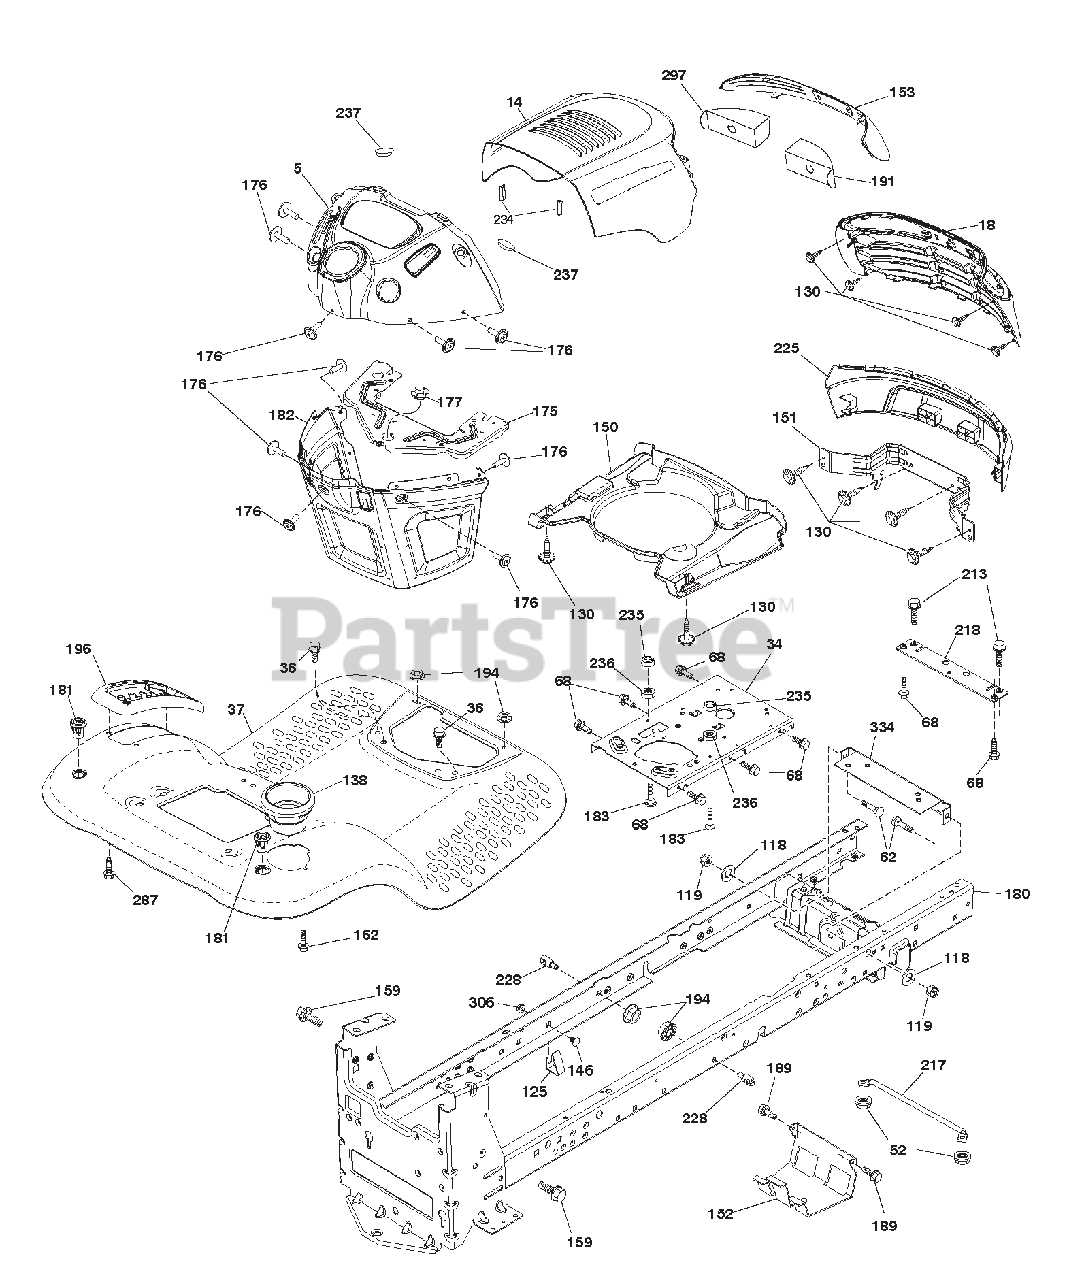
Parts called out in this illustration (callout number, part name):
18	GRILLE
34	PLATE.ENGINE.WELDED.CHASSIS
36	SCREW.5/16-18X3/4.SMGML.TAP/R
37	FENDER TLT W/CPH W/FW 422
52	Nut, Hex, Crownlock 5/16-18
62	Bolt 3/8-16 x 1 Gr. 5
68	SCREW.THDROL.5/16-18 X 1/2TYTT
118	WASHER.13/32 X 13/16 X 16 GA.
119	Nut, Hex, Crownlock 3/8-16
125	CLIP.FUEL.LINE
138	CUPHOLDER TL TEX 428
150	AIR DUCT.INTAKE.B&S
151	Bracket Pivot
152	SHIELD.BROWNING.W/TEX
153	LENS, ARIENS
159	SCREW.HEXWSH THDR3/8-16X3/4.BL
162	SCREW.HEX.WSH.HI-LO.1/4X1/2UNC
175	CROSSMEMBER.LT
176	SCREW.#10-24X5/8.RND.QUDRX.GIM
177	BUSHING.STEERING.LT
180	CHASS WLDMT TL 12 GA/2PC 18/22
181	BUSHING MNT FEND CRGO BLK TEX
182	DASH LOWER
183	BOLT.FIN.HEX.5/16-18 UNC X1-1/
189	SCREW.5/16-18X3/4.SMGML.TAP/BL
191	INSERT REFLECTIVE RH
194	Nut, Lock Hex Flange 5/16-18 u
196	CONSOLE ASSEMBLY
213	Bolt, Hex Head 5/16-18 x 3/4
217	ROD.PIVOT.HOOD
218	X-PIECE.HOOD.STOP.NON/STEALTH
225	BUMPER
228	STUD.FASTNER.W/'D'ANTI-ROTATIO
234	BUMPER HOOD
235	SPACER.FENDER
236	NUT.CENTER LOCK.5/16-18 UNC
237	PLUG.MOUNT.CARGO
287	SCREW.HEX.WASHEAD.1/4-20 X 3/8
297	INSERT REFLECTIVE LH
306	Nut, Hex, Flangelock 3/8-16
334	BRACKET ENGINE PLATE
